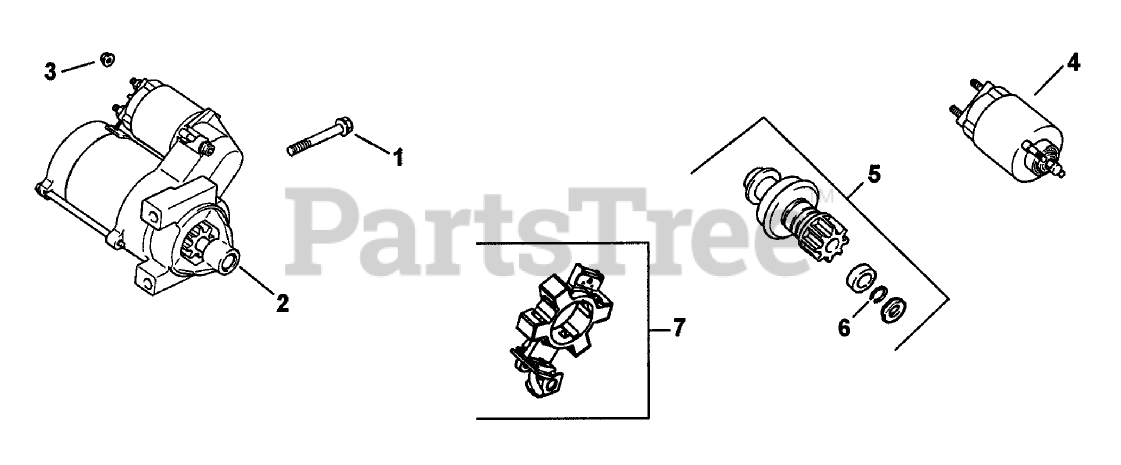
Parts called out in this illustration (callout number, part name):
1	SCREW-FLG (M8X1.25X80)
2	Solenoid Shift Starter ASM (Includes 4-7)
3	NUT-FLANGE (M8X1.25)
4	Solenoid Kit
5	Kit-Drive, Pinion (Includes 6)
6	RING-RETAINING
7	BRUSH HOLDER KIT
